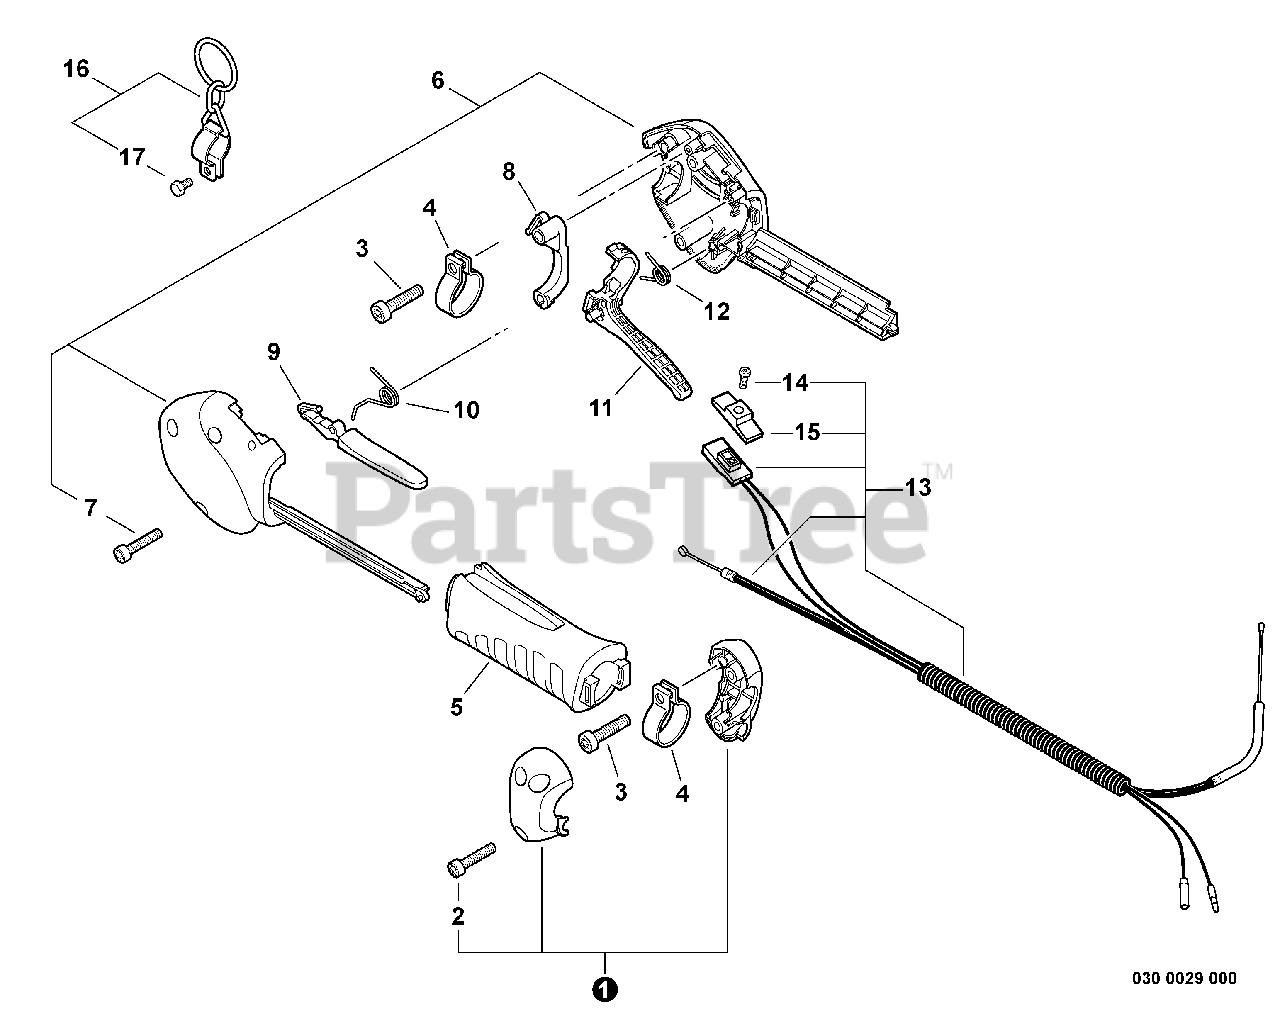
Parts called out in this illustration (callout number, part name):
1	FIXTURE SET, HANDLE
3	BOLT 5×20
5	GRIP, HANDLE
6	HANDLE KIT, CONTROL
8	LOCKOUT, THROTTLE
9	LEVER, THROTTLE LOCKOUT
10	SPRING, TORSION
11	TRIGGER, THROTTLE
12	SPRING, TORSION
13	CABLE ASSY, CONTROL
14	SCREW 3×10
15	KNOB, SWITCH - ORANGE
16	HANGER SET, HARNESS
17	BOLT 5×12
